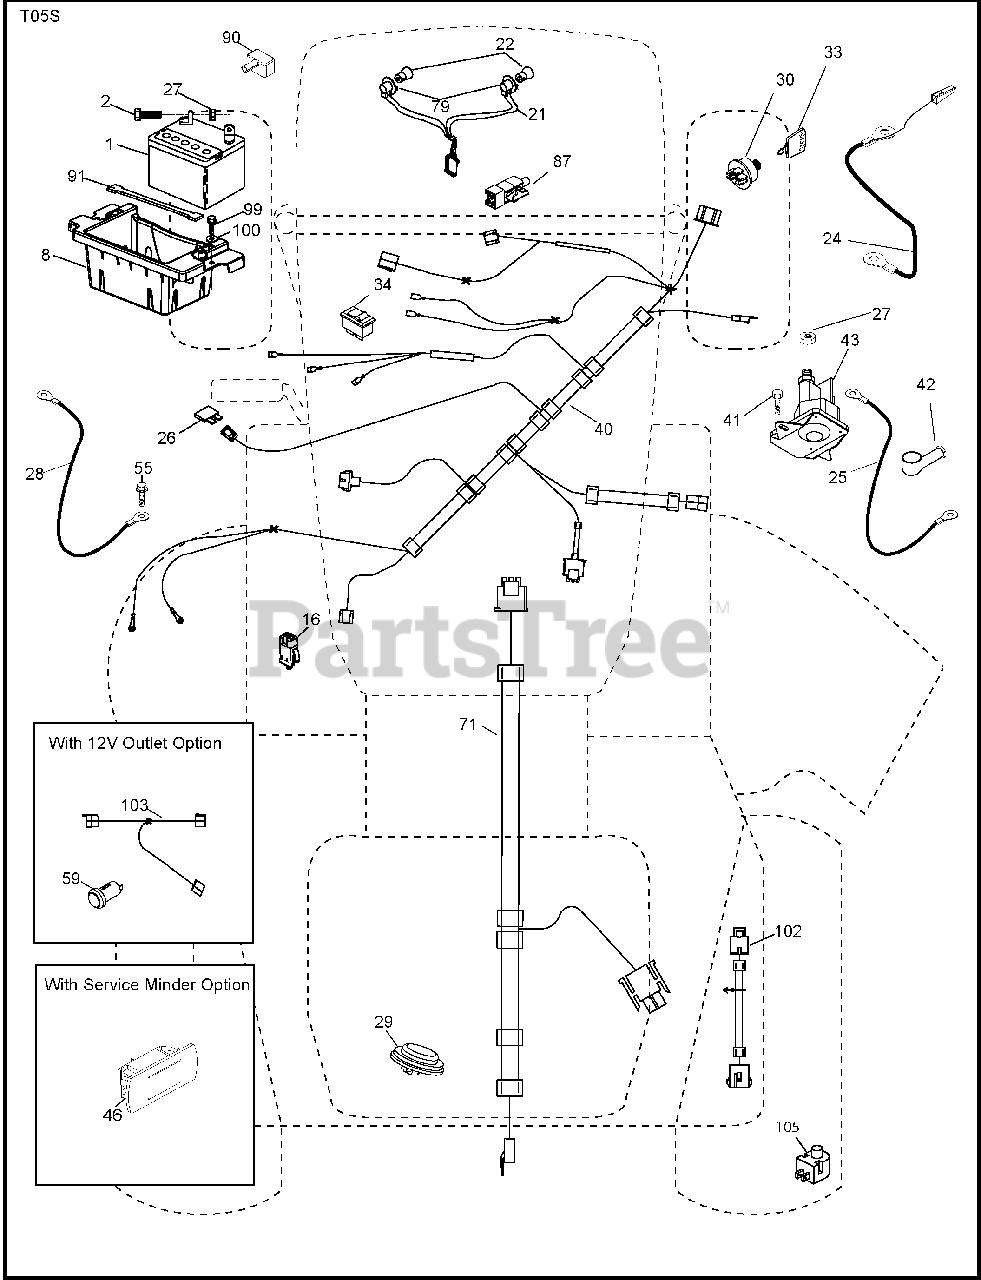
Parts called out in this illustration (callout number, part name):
1	Battery
2	Bolt Hex Head 1/4-20 x 3/4
8	Box Battery
16	Switch Interlock Push-In
21	Harness Socket Light W/4152J
22	Bulb Light
24	Cable Battery
25	Cable Starter
26	Fuse
27	Nut Keps Hex 1/4-20 unc
28	Cable, Ground
29	Switch, Seat
30	Switch, Ign
33	Key/Chain
34	Switch Light / Reset
40	Harness Ign. Dash
41	Screw Thd Cut 1/4-20 x 1/2
42	Cover, Terminal
43	Solenoid
46	Gauge Hourmeter
55	Screw Thdrol 5/16-18 x 3/4 TYTT
71	Harness Ign.
79	Socket Asm Bulb Twistlock
87	Switch Interlock Clutch Cable
90	Cover Terminal Battery
91	Strap Battery Mount Front
99	Screw Hexwsh Thdrol 1/4-20 x 3/4
100	Washer 9/32 x 7/8 x 16 Ga.
102	Harness Pigtail K46 TEX ROS
105	Switch Reverse TT Pedal Control
